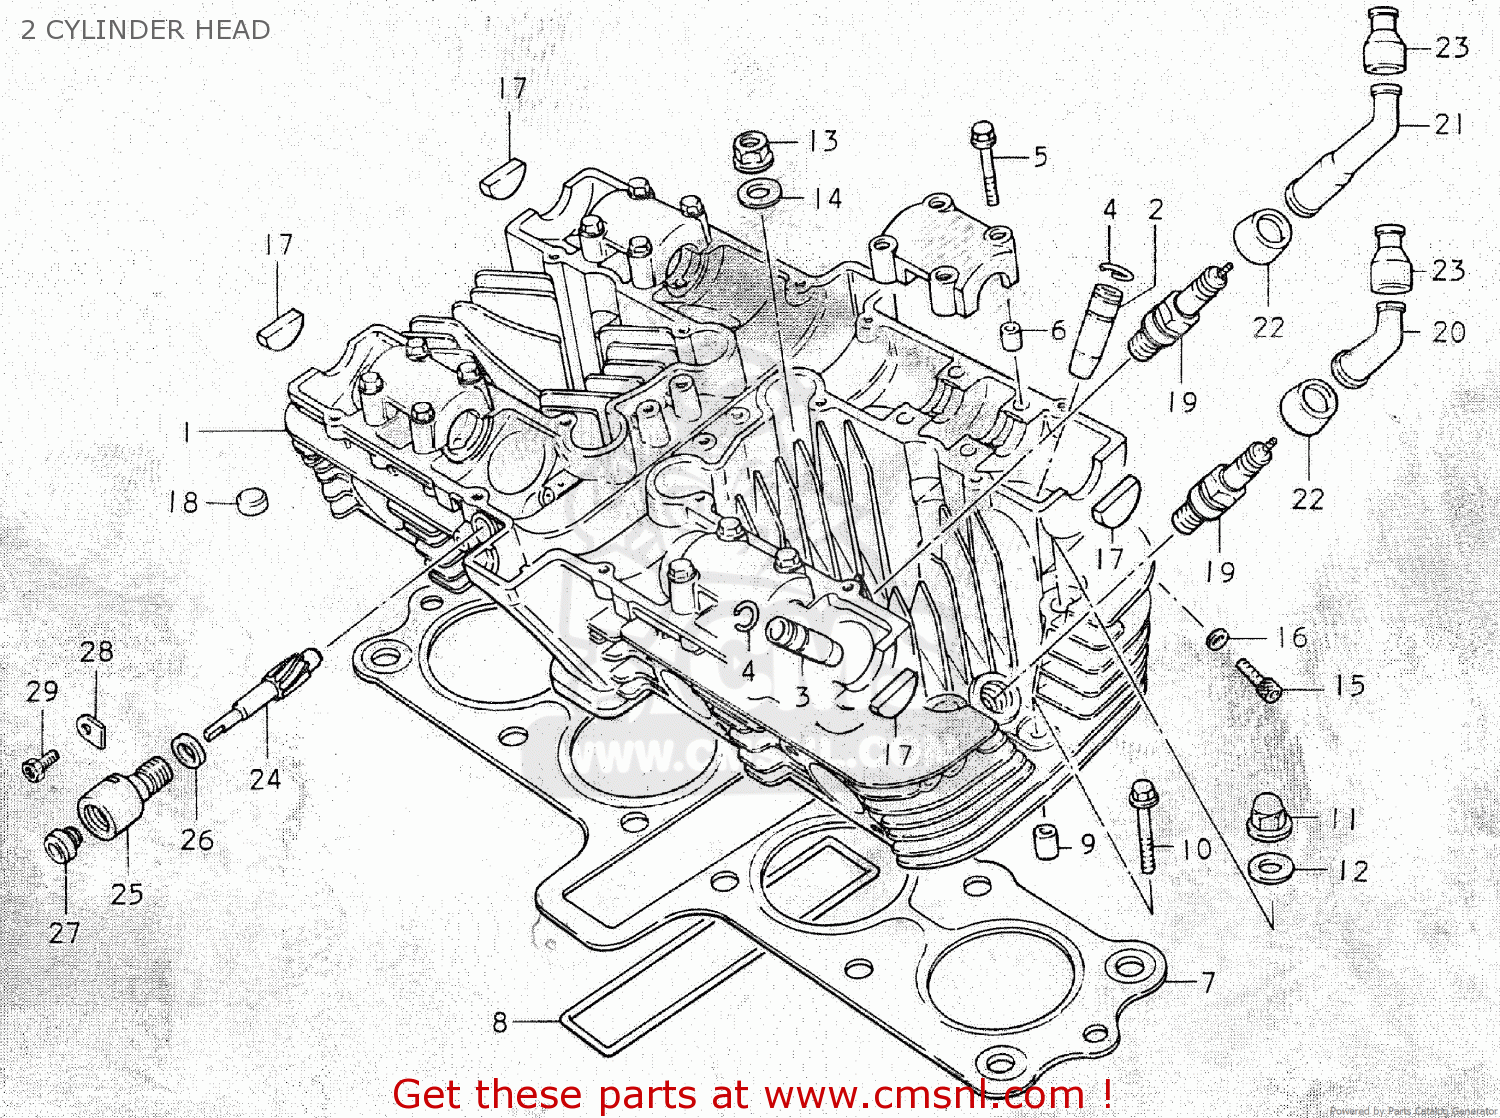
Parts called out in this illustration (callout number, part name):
1	HEAD ASSEMBLY,CYLINDER
2	GUIDE,VALVE
3	GUIDE,VALVE
4	RING,SNAP
5	BOLT(6X39)
6	PIN(6.2X8X11)
7	GASKET,CYLINDER HEAD (NAS)
8	O RING(D:3,ID:26X157)
9	PIN
10	BOLT,UNDER
11	NUT
12	GASKET(10.5X22X2) (NAS)
13	NUT
14	WASHER(10.5X22X2.3)
15	BOLT
16	GASKET(5.3X9.3X1.2) (NAS)
17	PLUG
18	PAD
19	PLUG,SPARK
20	CAP,SPARK PLUG
21	CAP ASSY,SPARK PLUG
22	SEAL,SPARK PLUG
23	SEAL,SPARK PLU
24	GEAR,TACHOMETER DRIVEN
25	SLEEVE,TACHOMETER DRIVE
26	SEAL,TACHOMETER DRIVEN
27	SEAL
28	PLATE,TACH DRIVE GEAR SLEEVE
29	SCREW(5X12)
